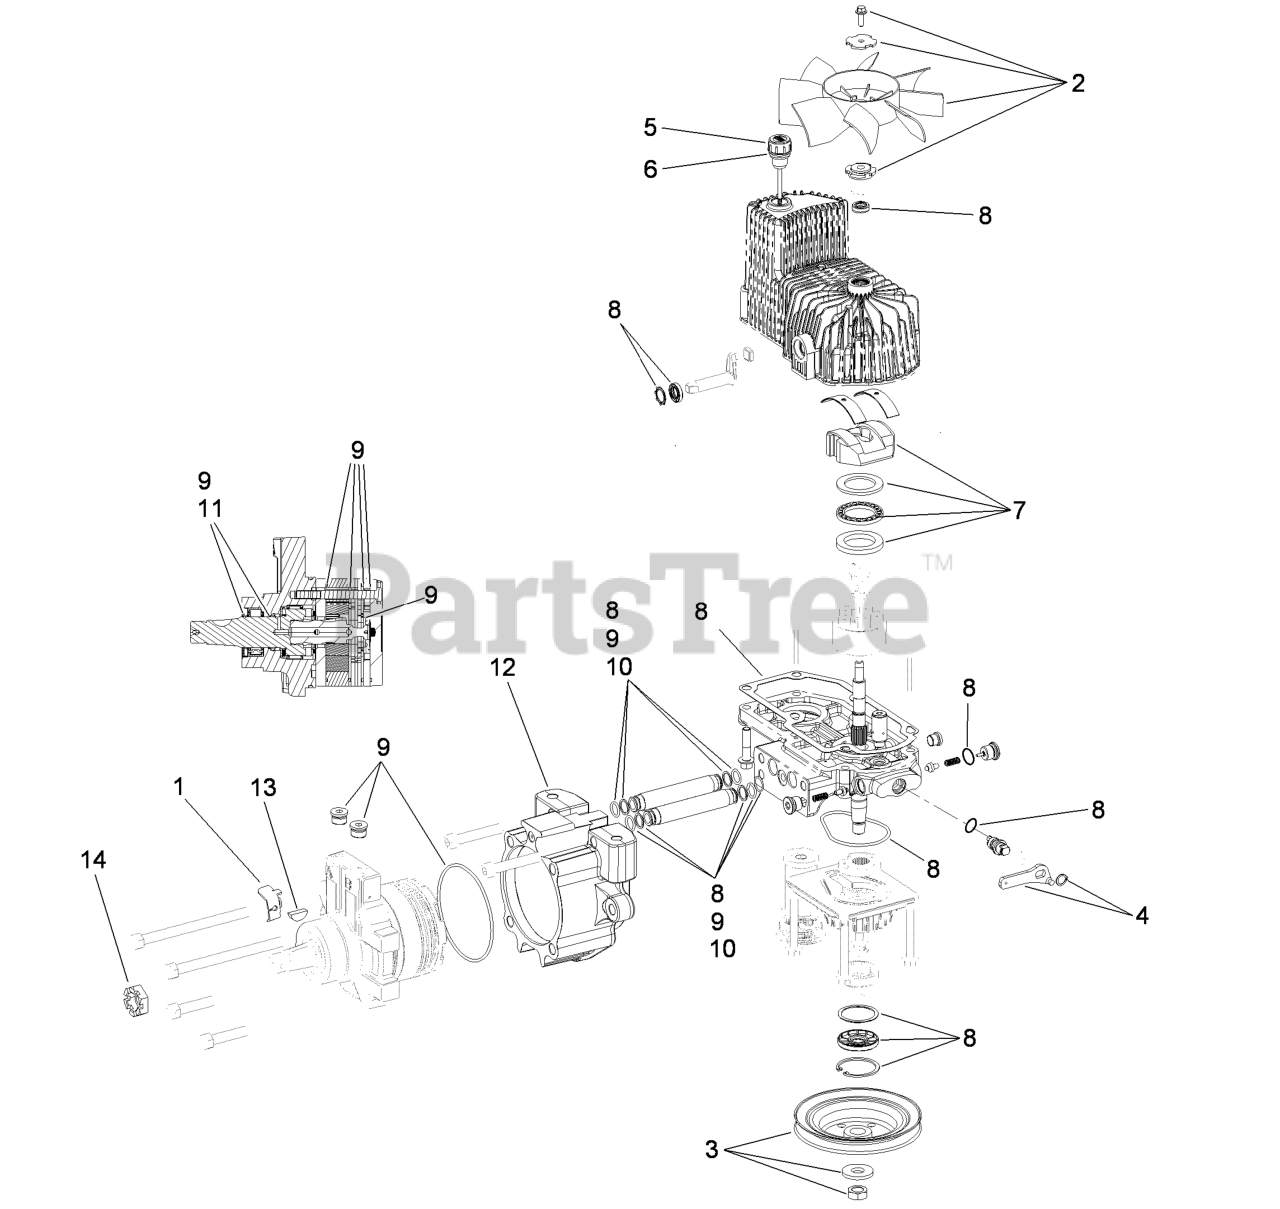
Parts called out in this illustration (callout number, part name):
1	BRACKET-ANCHOR, CABLE
2	FAN KIT
3	PULLEY KIT
4	HANDLE-BYPASS VALVE, HYDRO
5	DIPSTICK-HYDRO W/GASKET
6	GASKET-DIPSTICK, HYDRO
7	SWASH BLOCK KIT
8	PUMP SEAL KIT
9	MOTOR SEAL KIT
10	TUBE SEAL KIT
11	OUTPUT SHAFT SEAL KIT
12	CUP-NOSE
13	KEY-WOODRUFF
